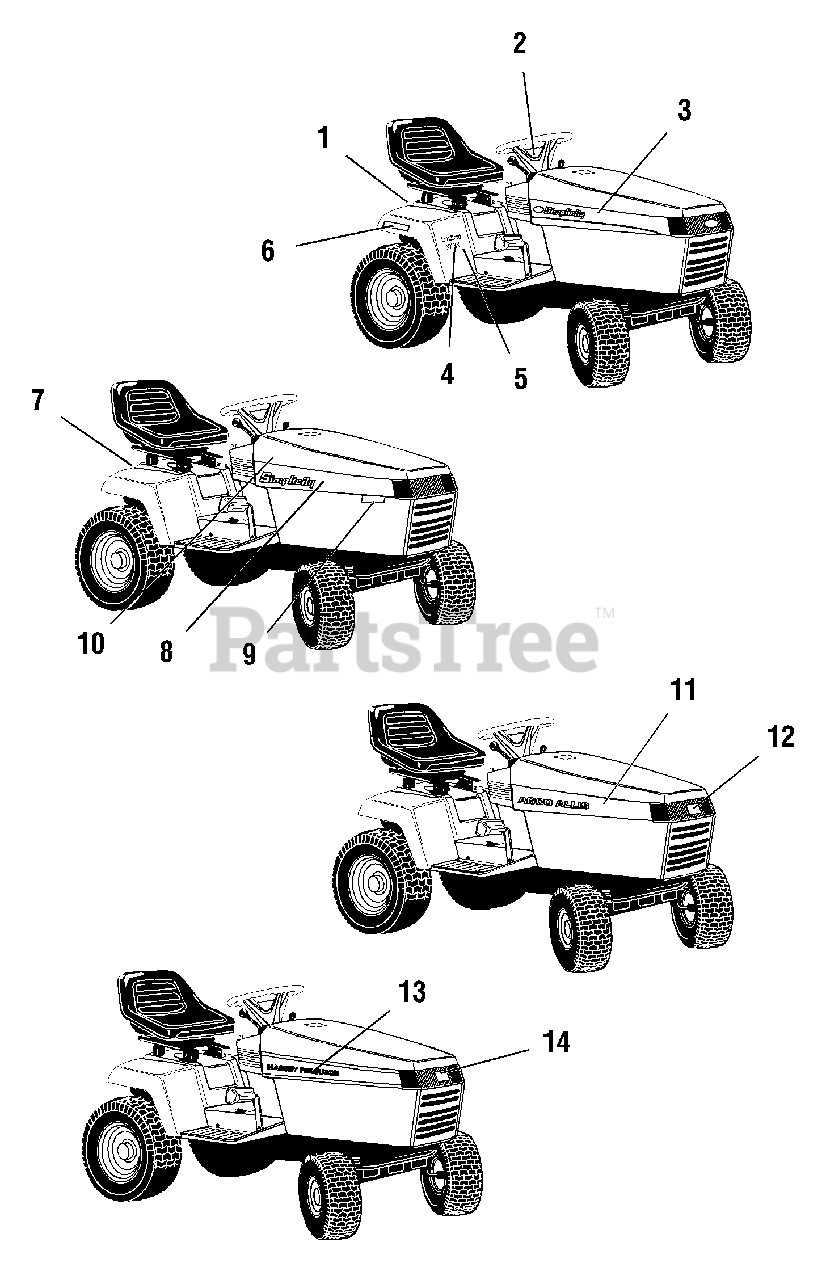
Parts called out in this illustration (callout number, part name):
1	DECAL, Simplicity Logo
2	DECAL, Simplicity Icon
3	DECAL, RH Hood Stripe
3	DECAL, LH Hood Stripe
4	DECAL, Landlord
5	DECAL, Liquid Cooled
6	DECAL, Automatic Control Traction
7	DECAL, Simplicity Logo
8	DECAL, RH Hood, Simplicity Landlord
8	DECAL, LH Hood, Simplicity Landlord
9	DECAL, Model, Simplicity Landlord - Hydro 16V-Twin
9	DECAL, Model, Simplicity Landlord - Hydro 18V-Twin
9	DECAL, Model, Simplicity Landlord - Hydro 17LC
10	DECAL, Liquid Cooled
11	DECAL, LH Hood - AGCO-Allis 1718VH
11	DECAL, RH Hood - AGCO-Allis 1718VH
11	DECAL, LH Hood - AGCO-Allis 1716VH
11	DECAL, RH Hood - AGCO-Allis 1716VH
11	DECAL, RH Hood - AGCO-Allis 1717H
11	DECAL, LH Hood - AGCO-Allis 1717H
12	DECAL, AGCO Allis Logo
13	DECAL, RH Hood, Massey Ferguson 2718H
13	DECAL, LH Hood, Massey Ferguson 2718H
13	DECAL, RH Hood, Massey Ferguson 2716H
13	DECAL, LH Hood, Massey Ferguson 2716H
14	DECAL, Massey Ferguson Logo
